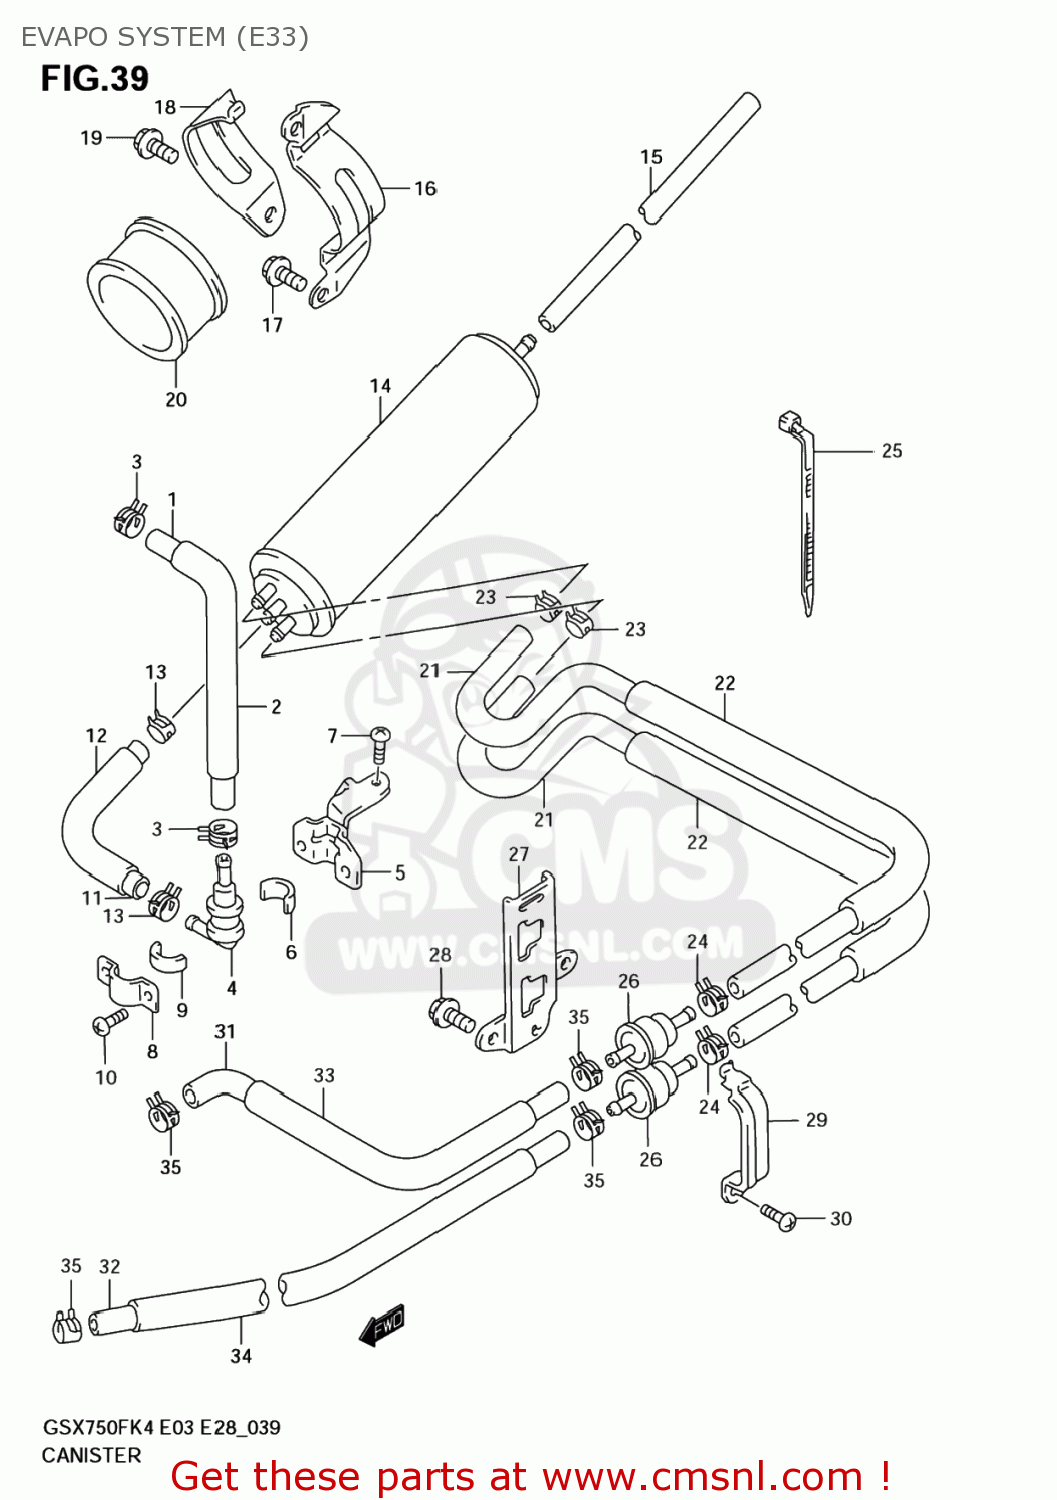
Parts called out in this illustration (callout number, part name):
1	HOSE(5.4X11.4X600)
2	PROTECTOR(14.5X15.5X600)
3	CLIP
4	VALVE,FUEL TANK BREATHER
5	PLATE,BREATHER VALVE
6	CUSHION
7	SCREW 6X12
8	PLATE,FUEL TANK BREATHER NO.2
9	CUSHION
10	SCREW
11	HOSE,VALVE & CANISTER CHARGE
12	PROTECTOR(14.5X15.5X600)
13	CLIP
14	CANISTER ASSY,CHARCOAL
15	HOSE(7X12X600)
16	BRACKET,CANISTER MOUNTING
17	BOLT
18	HOLDER,CANISTER
19	SCREW 6X12
20	CUSHION,CANISTER
21	HOSE,CSTR & PURGE VALVE
22	PROTECTOR(14.5X15.5X600)
23	CLIP
24	CLIP
25	CLAMP(L:95)
26	VALVE,CANISTER PURGE
27	BRACKET,CANISTER PURGE VALVE
28	BOLT
29	HOLDER,CANISTER PURGE
30	SCREW
31	HOSE,CARB & PURGE NO.1
32	HOSE,CARBURETOR & PURGE NO.2
33	PROTECTOR(14.5X15.5X600)
34	HOSE
35	CLIP
